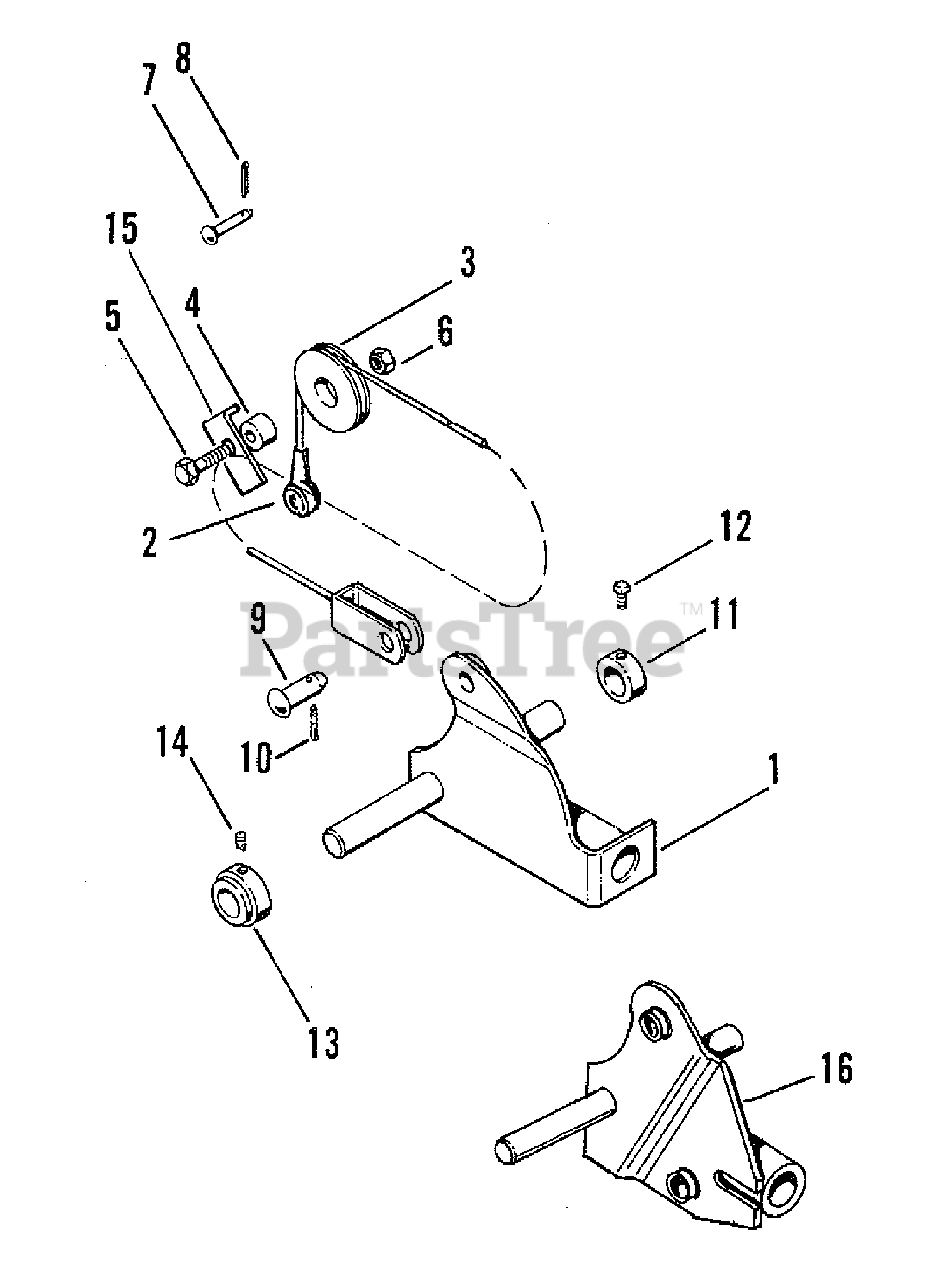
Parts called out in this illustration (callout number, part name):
1	LIFT LEVER ASSEMBLY (929 Only)
2	LIFT CABLE ASSEMBLY
5	HEX CAPSCREW, 3/8"-16 x 1-1/4" Lg.
6	HEX JAM NUT, 3/8"-16
7	PIN
8	COTTER PIN, 3/32 x 7/8" Lg
10	COTTER PIN, 1/8 x 1" Lg.
11	SET COLLAR
12	SET SCREW, 5/16-18 x 3/8" Lg.
14	SET SCREW
15	CABLE GUARD (Mfg. No. 984 Only)
16	LIFT LEVER ASSEMBLY (Mfg. No. 984 Only)
